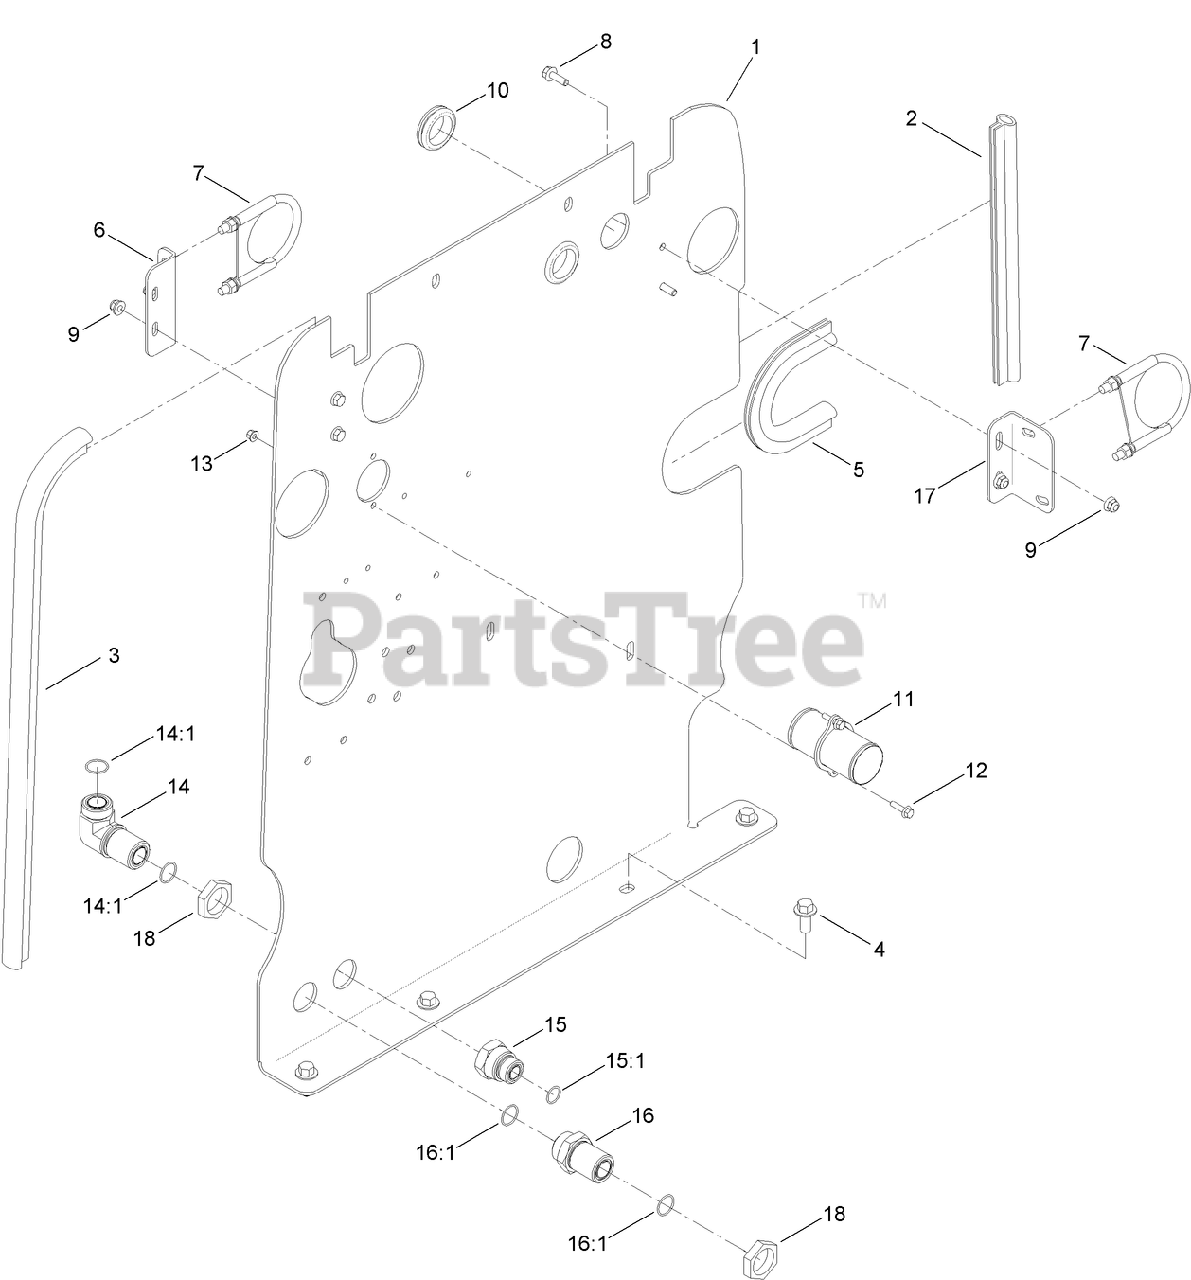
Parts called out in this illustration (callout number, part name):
1	BULK HEAD ASM
2	SEAL-BULB, LH
3	SEAL-BULB, RH
4	SCREW-HHF
5	SEAL-BULB
6	PLATE-SUPPORT, EXHAUST
7	CLAMP-GUILLOTINE
8	SCREW-HHF
9	NUT-LOCK, HHF
10	Grommet
11	TUBE-BULKHEAD, RADIATOR
12	SCREW-HHF
13	NUT-FLANGE, NI
14	FITTING-ELBOW, 90
14:1	O-RING
15	FITTING-REDUCER
15:1	O-RING
16	ADAPTER-HYD
16:1	O-RING
17	PLATE-SUPPORT, CHARGE AIR
18	NUT-BULKHEAD
